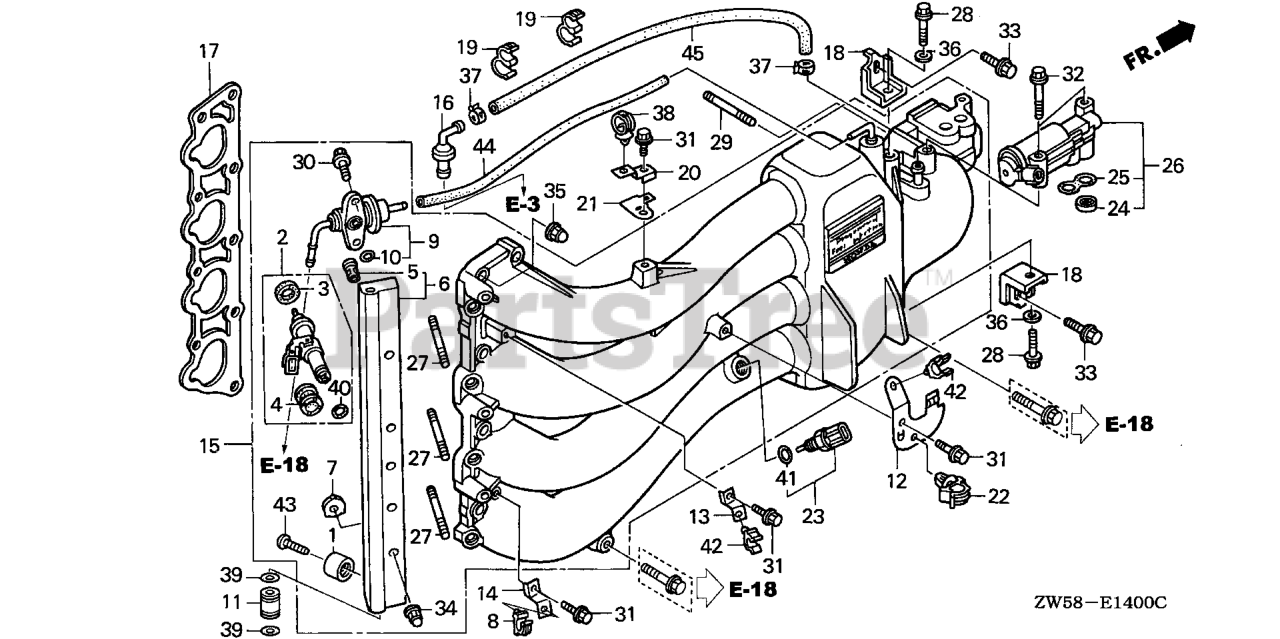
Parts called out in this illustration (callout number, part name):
1	METAL, ANODE
2	INJECTOR SET
3	SEAL RING, INJECTOR (OTSUKA)
4	CUSHION RING, INJECTOR (OTSUKA)
4	CUSHION RING, INJECTOR (NOK)
5	MESH, FUEL FILTER
6	LINE, FUEL
7	INSULATOR, FUEL PIPE
8	CLIP, TUBE
9	REGULATOR ASSY., PRESSURE
10	O-RING, PRESSURE REGULATOR
11	JOINT, FUEL PIPE
12	BRACKET, HOSE CLAMP (A)
13	BRACKET, HOSE CLAMP (B)
14	BRACKET, TUBE CLAMP
15	MANIFOLD ASSY., IN. *NH8* (DARK GRAY)
16	VALVE ASSY., PCV
17	GASKET, IN. MANIFOLD
18	STAY, IN. MANIFOLD (A)
19	CLAMP, TUBE (7.5-11.5) (BLACK)
20	BRACKET, CLIP A
21	BRACKET, CONNECTOR (D)
22	CLAMP, WIRE
23	SENSOR ASSY., AIR TEMPERATURE
24	FILTER, ELECTRONIC AIR CONTROL VALVE (TOYO ROKI)
25	GASKET, ELECTRONIC AIR CONTROL VALVE (KEIHIN)
26	VALVE ASSY., ELECTRONIC AIR CONTROL
27	BOLT 2, STUD (6X35)
28	BOLT, SPECIAL (8X16)
29	BOLT, STUD (8X35)
30	BOLT, FLANGE (6X14)
31	BOLT, FLANGE (6X12)
32	BOLT, FLANGE (8X45)
33	BOLT, FLANGE (8X18)
34	NUT, CAP (6MM)
35	NUT, CAP (10MM)
36	WASHER (14X23)
37	CLAMP, TUBE (D12)
38	CLIP, HARNESS
39	O-RING (7.8X1.9) (ARAI)
40	O-RING
40	O-RING (7.3X2.2) (NOK)
42	CLAMP, PURGE HOSE
43	SCREW, PAN (6X18)
44	BULK HOSE, FUEL (3.5X3000) (3.5X120)
45	BULK HOSE, VACUUM (7.3X1000) (7.5X160)
